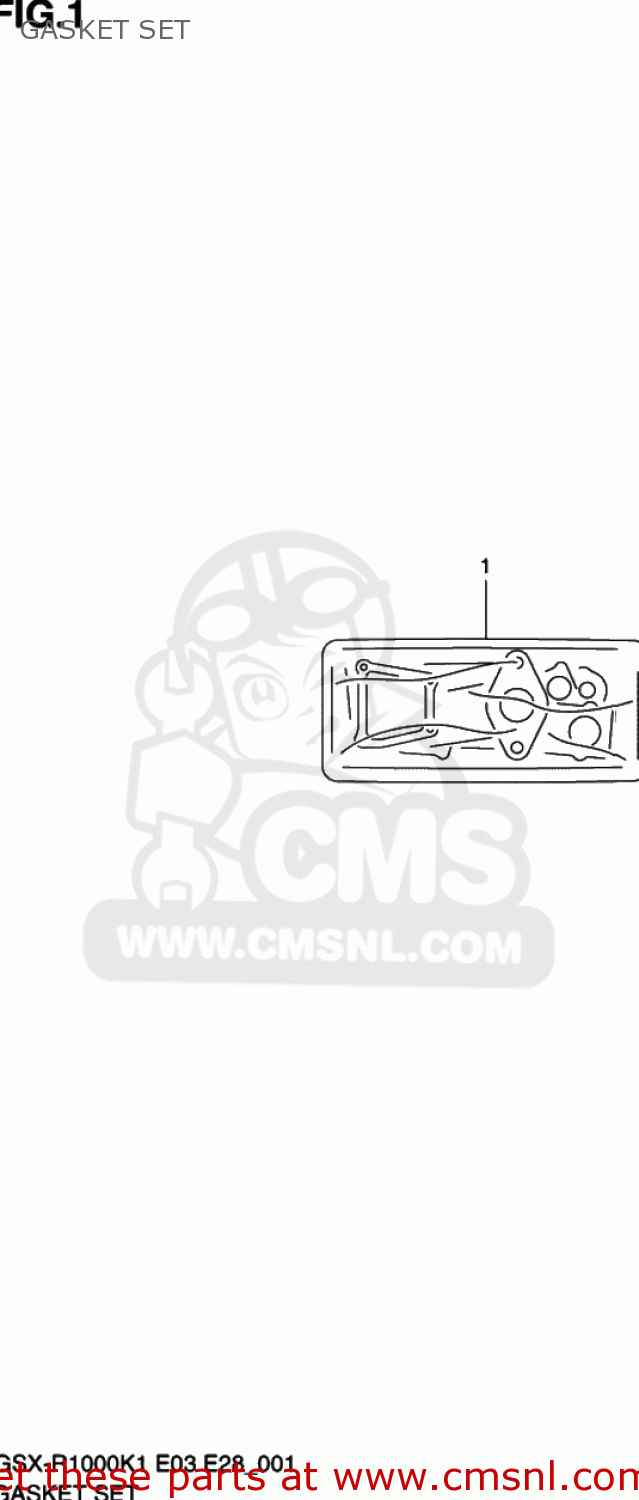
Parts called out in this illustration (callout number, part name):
1	GASKET SET (NAS)
2	GASKET,CYLINDER HEAD (NAS)
3	GASKET,CYL HEAD COVER NO.1 (NAS)
4	GASKET,CYL HEAD COVER NO.2
5	GASKET,2ND AIR PASSAGE (NAS)
6	WASHER(10.6X25.5X2.3)
7	GASKET,CL COVE (NAS)
8	GASKET,STARTER CLUTCH COVER
9	O RING(D:3.1,ID:32.7)
10	GASKET,START IDLE GEAR CAP (NAS)
11	GASKET,MAGNETO COVER (NAS)
12	GASKET,BREATHER COVER (NAS)
13	GASKET,OIL PAN (NAS)
14	GASKET,TENSIONER ADJUSTER (NAS)
15	GASKET,MUFFLER JOINT (NAS)
16	GASKET,EXHAUST PIPE
17	O RING(D:1.9,ID:7.8)
18	O RING,OIL PUMP
19	O RING(D:2.62,ID:20.3)
20	O RING(D:2.4,ID:11.8)
21	O RING,FUEL PUMP
